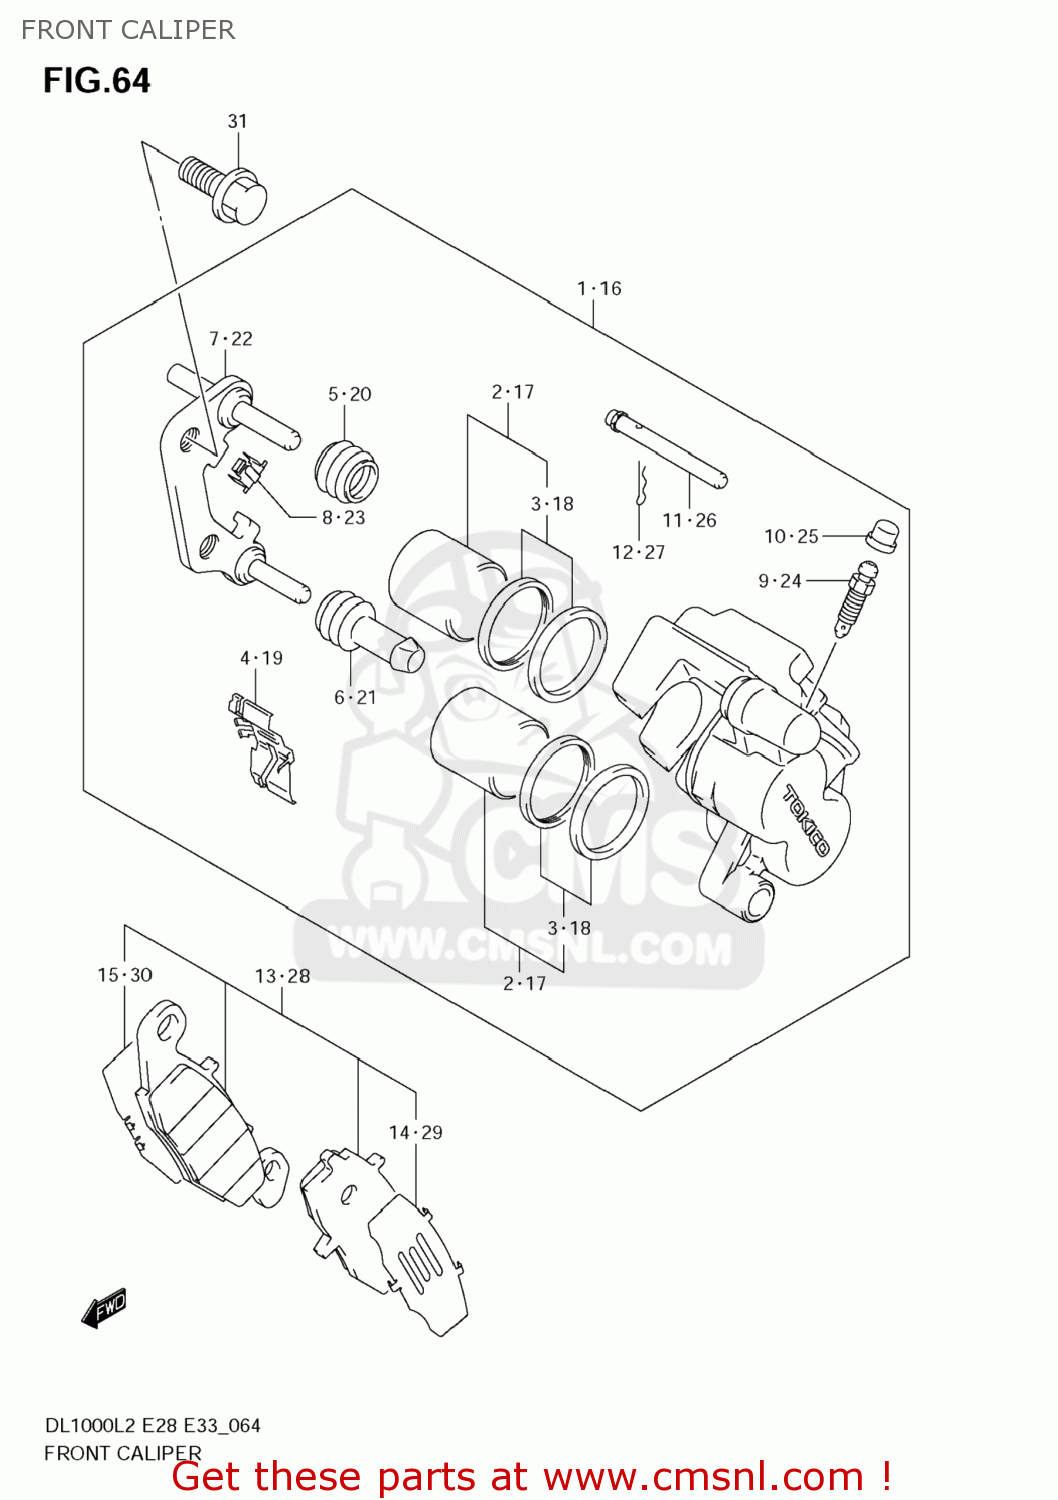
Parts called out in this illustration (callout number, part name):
1	CALIPER ASSY,FR,R
2	PISTON SET
3	SEAL SET,PISTON
4	SPRING,PAD,R
5	BOOT,AXLE
6	INSULATOR,AXLE
7	CARRIER,CALIPER,R
8	GUIDE,PAD
9	BLEEDER
10	CAP,BLEEDER PLUG
11	PIN,PAD
12	CLIP,PAD PIN
13	PAD & SHIM SET,R (NAS)
14	SHIM,PAD
15	SHIM,PAD NO.2
16	CALIPER ASSY,FR,L
17	PISTON SET
18	SEAL SET,PISTON
19	SPRING,PAD,L
20	BOOT,AXLE
21	INSULATOR,AXLE
22	CARRIER,CALIPER,L
23	GUIDE,PAD
24	BLEEDER
25	CAP,BLEEDER PLUG
26	PIN,PAD
27	CLIP,PAD PIN
28	PAD & SHIM SET,L (NAS)
29	SHIM,PAD
30	SHIM,PAD NO.2
31	BOLT
